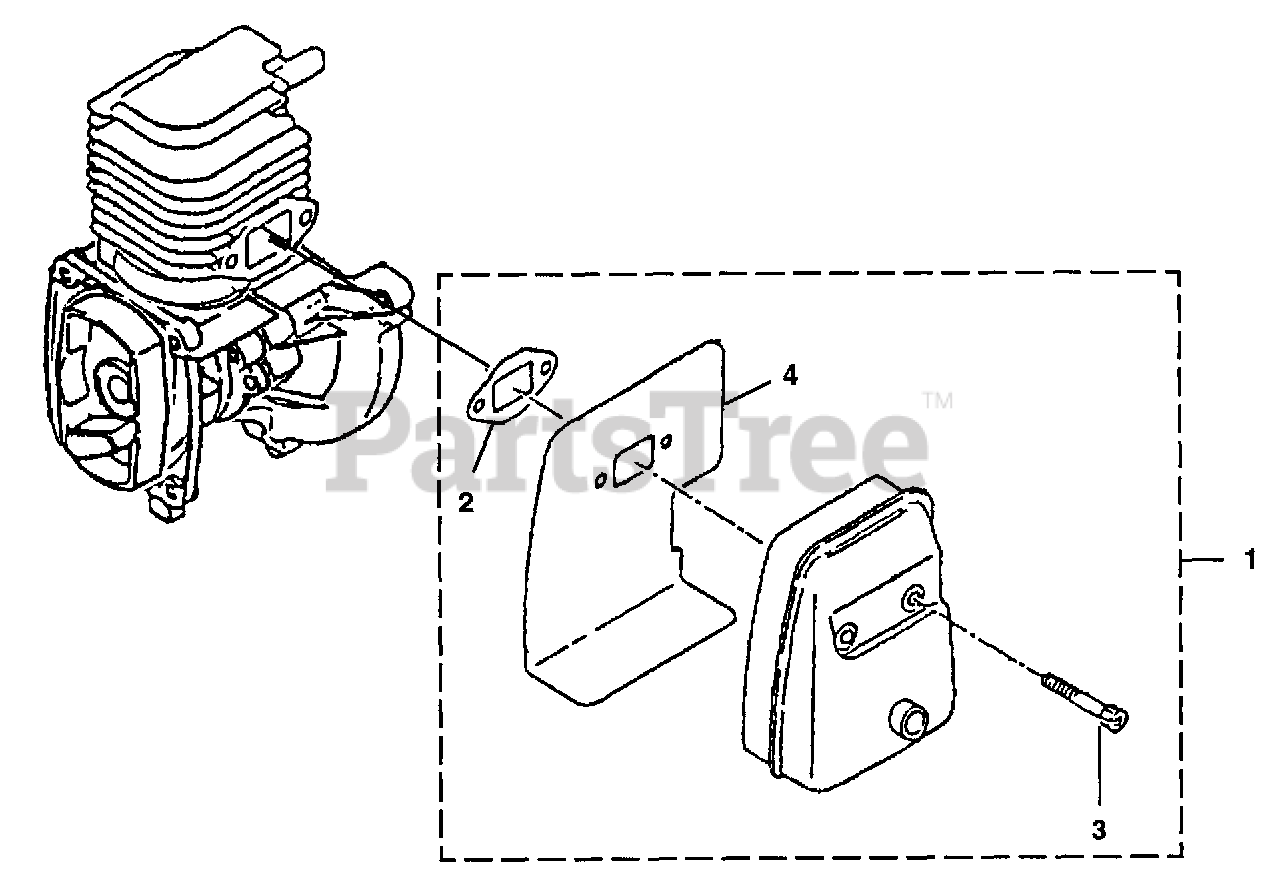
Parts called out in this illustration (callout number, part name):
1	MUFFLER ASSEMBLY
2	GASKET-Muffler
3	SCREW-Socket Hd. (M5 x 55)
4	INSULATOR-Muffler
